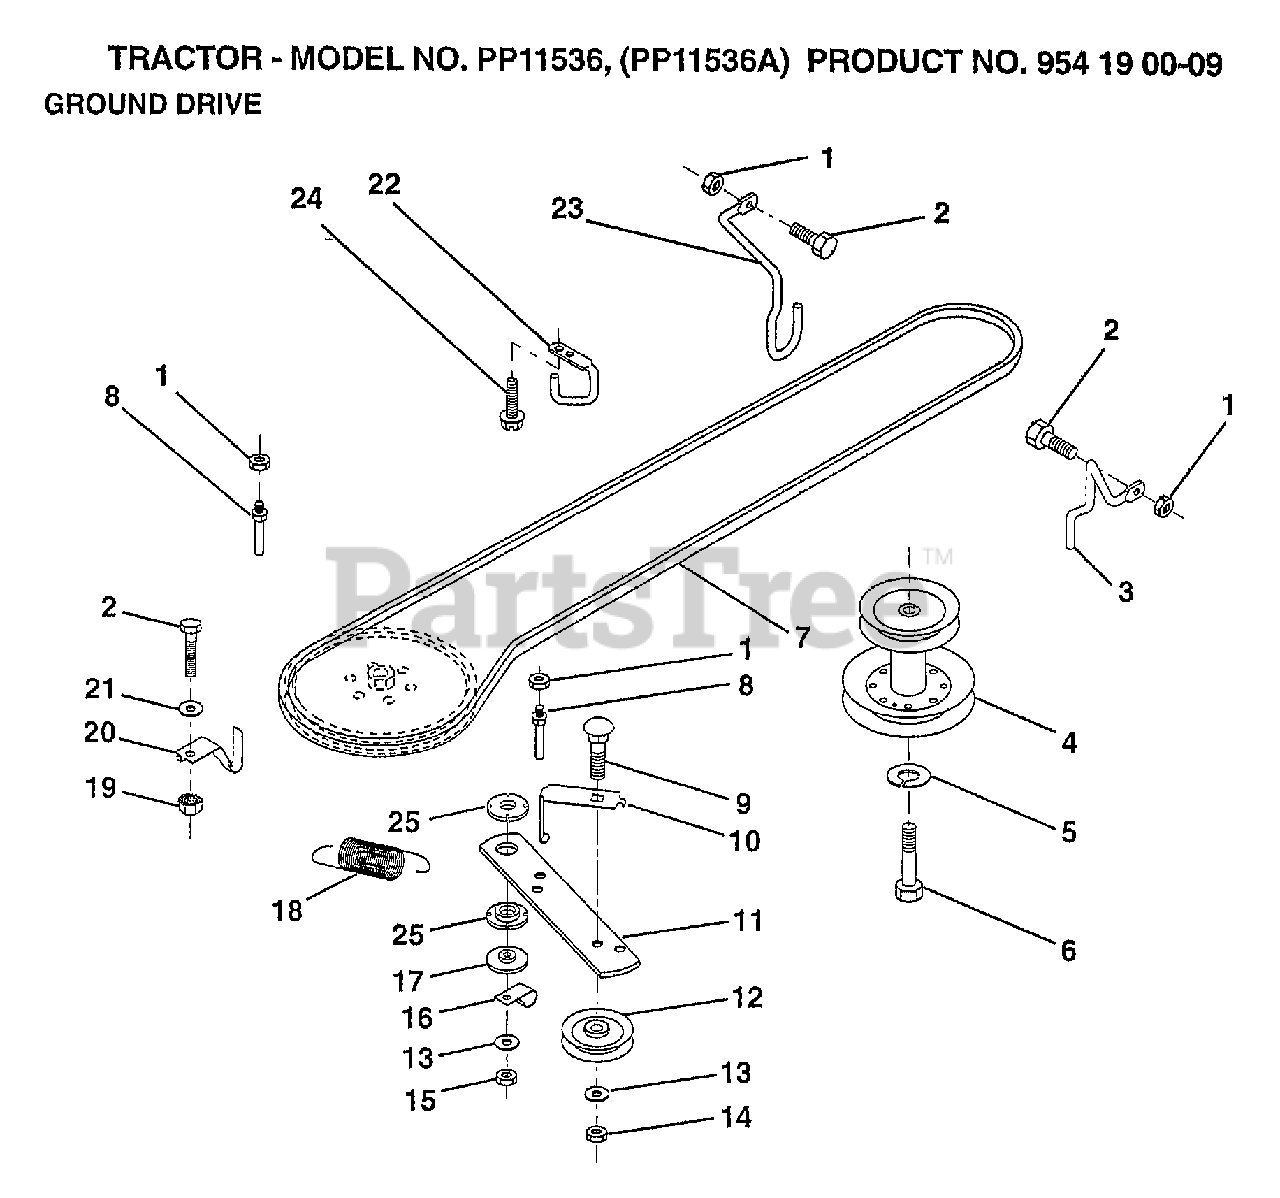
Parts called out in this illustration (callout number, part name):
2	BOLT
3	KEEPER RH
4	PULLEY.ENGINE.LR
5	LOCKWASHER
6	HEX BOLT
7	V BELT
8	"KEEPER,DRIVE BELT"
9	BOLT
10	"KEEP,IDLER DR BEL"
11	ARM-IDLER.DR.GRND
12	PULLEY.IDLER.FLAT
13	WASHER
14	LOCKNUT
16	"CLIP,INSULATOR"
17	SPACER
20	KEEPER.BELT.T/A
21	WASHER
22	"KEEPER,FRA DR BEL"
23	KEEPER MOWER LH
24	SCREW
25	BUSHING.NYLON
